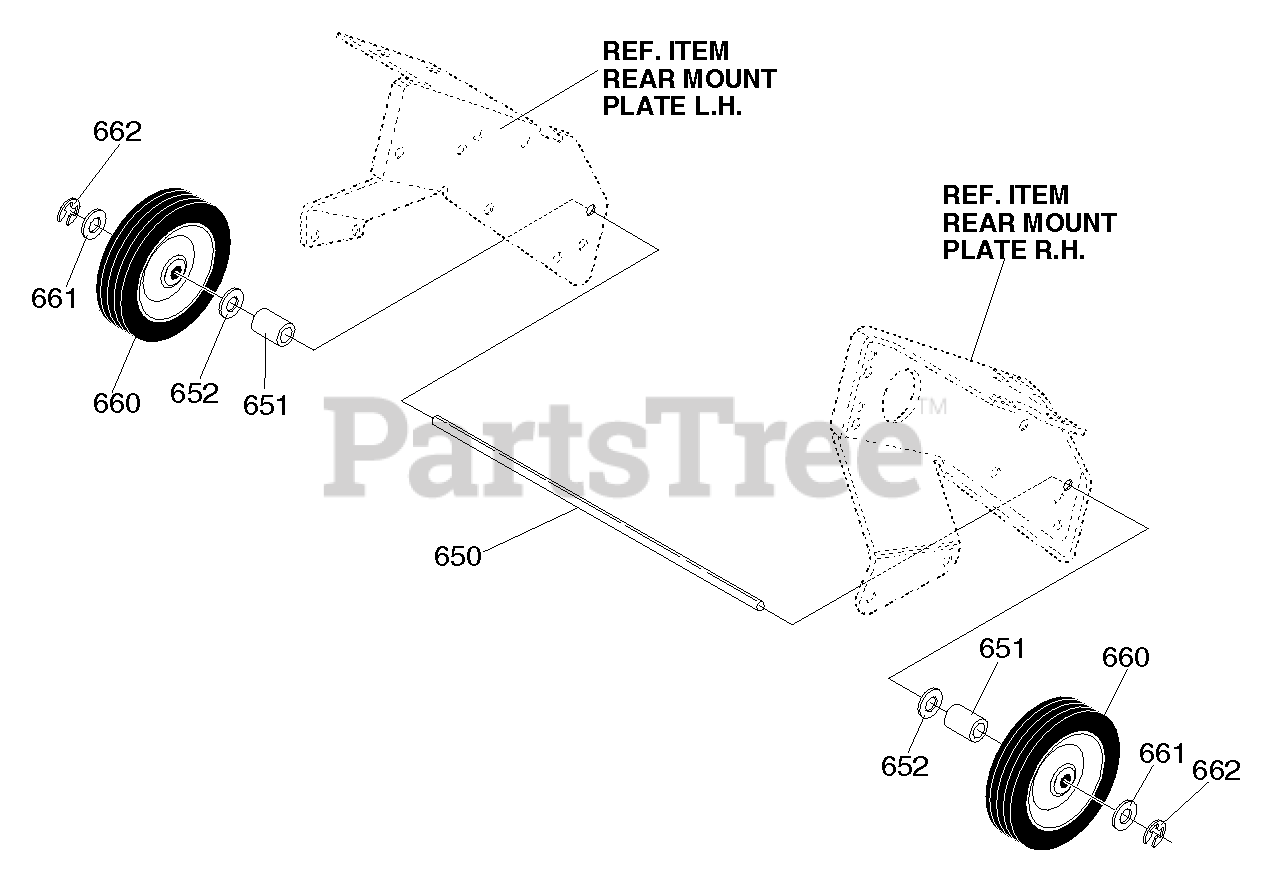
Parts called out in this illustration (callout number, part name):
650	AXLE SHAFT
651	SPACER, SLEEVE
652	FLATWASHER .406 X .81 X .065
660	TIRE & RIM 8 X 1.75
661	FLATWASHER .406 X .81 X .065
662	RING, RET.
